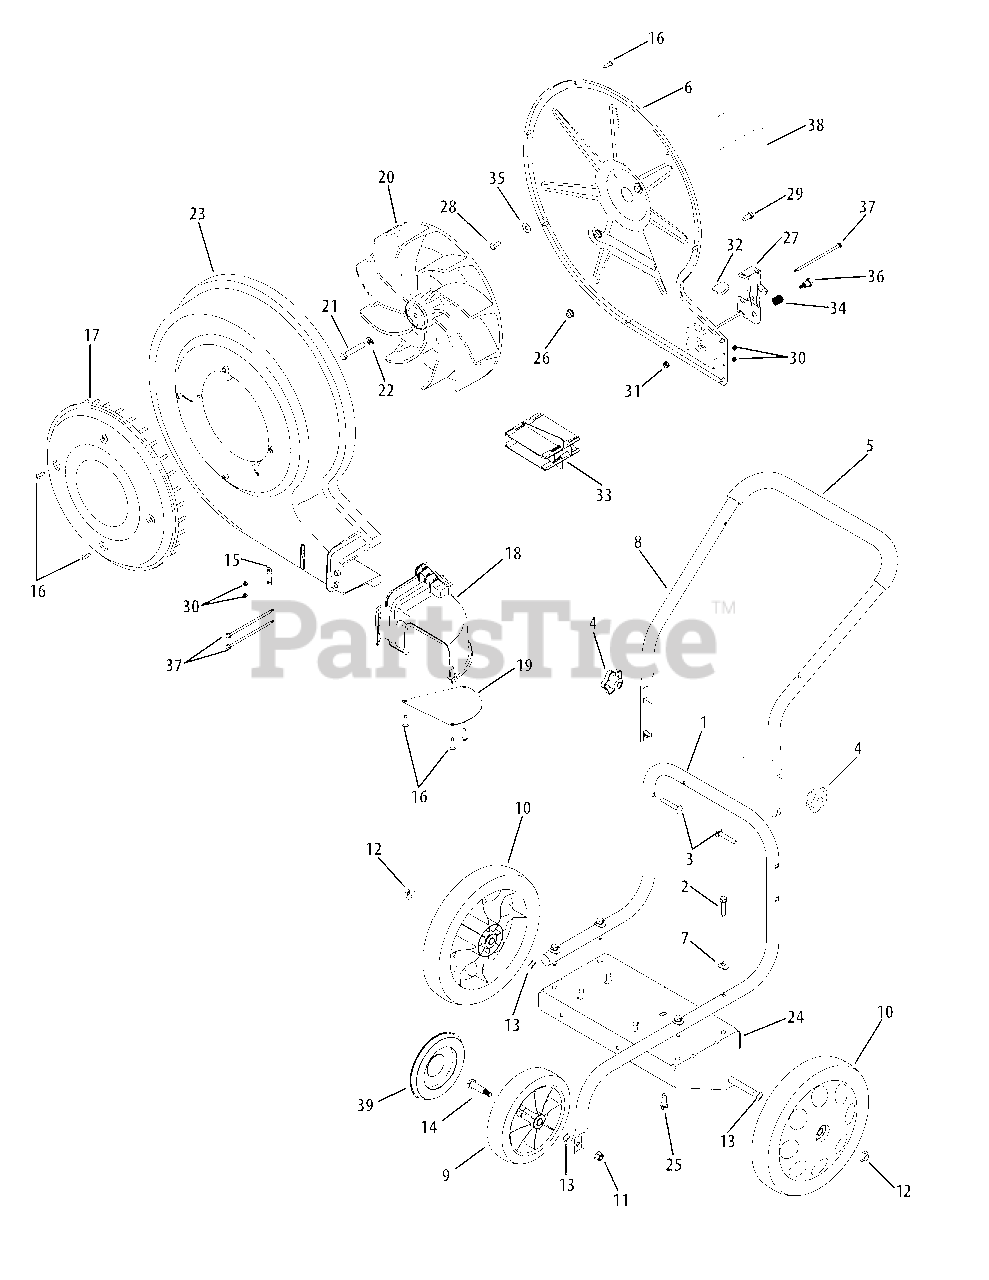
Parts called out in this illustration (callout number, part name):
2	Hex Screw, 5/16-18 x 1.50
3	Carriage Screw, 5/16-18 x 2.00
4	Star Knob, 5/16-18
5	Foam Grip, .970 x 25
7	Saddle Washer, .320 x .93 x .060
9	Wheel, 8 x 2.125, Grey
10	Wheel, 12 x 2.125, Grey
11	Flange Lock Nut, 3/8-16
12	Push Cap, 1/2"
13	Wave Washer, .510 x .750 x .017
14	Shoulder Screw, .498 x 1.445
15	Guide Plate
16	Hex Screw, 12-16 x .75
17	Blower Cover, Black
18	Chute Assembly
20	Impeller Assembly
21	Hex Screw, 3/8-24 x 2.25
22	Lock Washer, 3/8
23	Blower Housing
25	Sems Screw, 3/8-16 x 1.000
26	Flange Lock Nut, 5/16-18
28	Hex Bolt, 5/16-24 x 1.00 (208cc )
29	Hex Bolt, 5/16-18 x .75
30	Hex Lock Nut, #8-32
31	Flange Lock Nut, 1/4-20
32	Height Adjustment Knob
33	Louver Plate
34	Comp. Spring, .515 x .641 x .95
35	Bell Washer, .340 x .872 x .060
36	Shoulder Screw, .437 x .50 x 1/4-20
37	Shoulder Screw, .18 x 4.8 x 8-32
38	Engine Plate (208cc engine)
39	Hubcap
